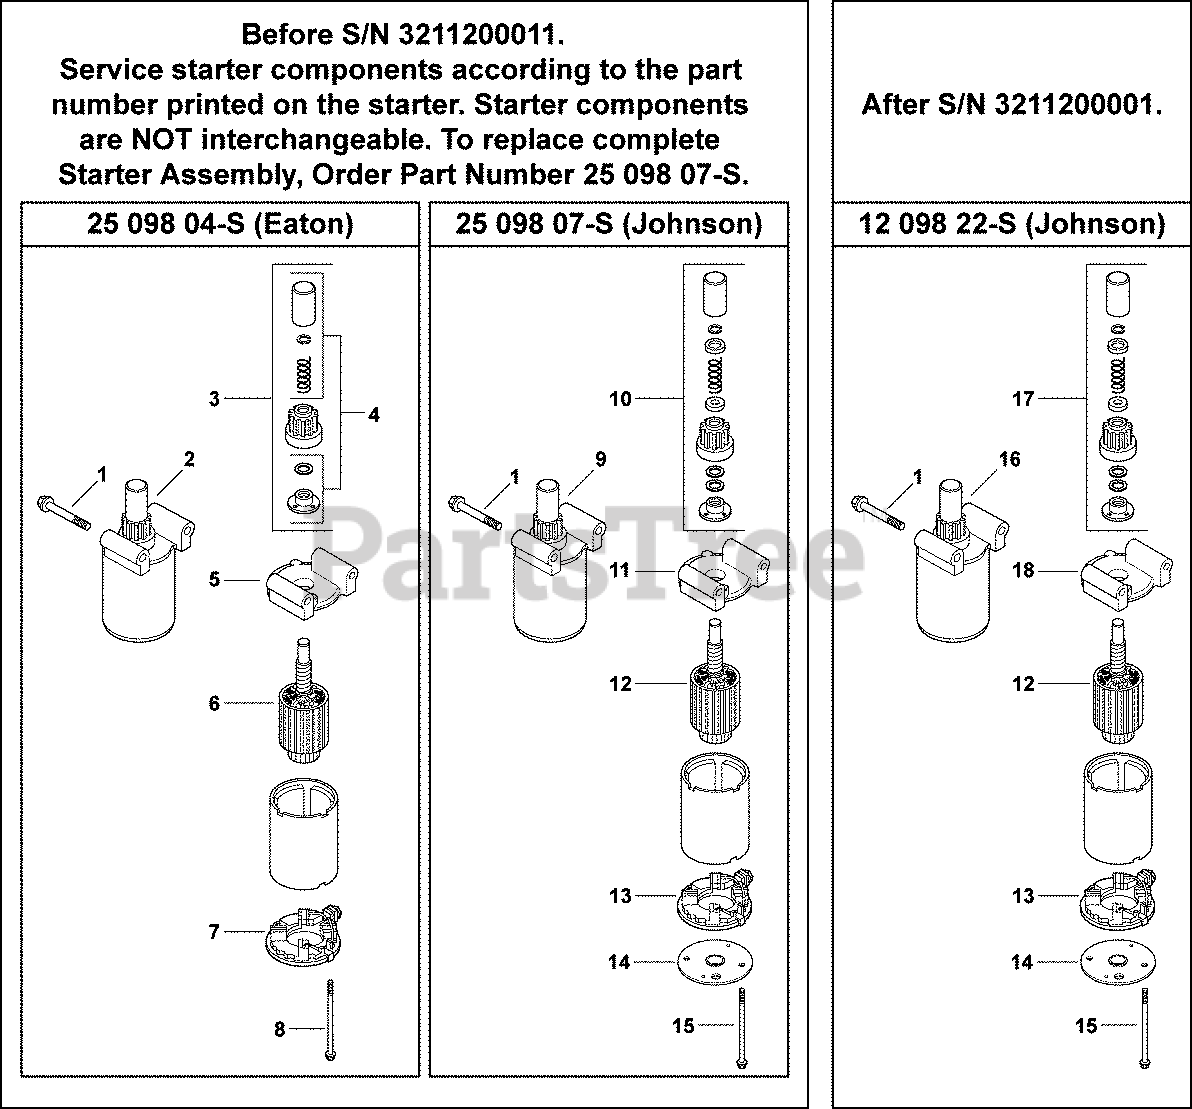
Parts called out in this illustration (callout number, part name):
1	SCREW, FLG M8X1.25X70
3	KIT,DR W/GEAR (FASCO/V.WEISE/W&G)(#DSC)
4	KIT, DR PTS(FASCO/V.WEISE/W&G) - DISC.
5	CAP, DRIVE END - DISCONTINUED
6	ARMATURE - (#DSC)
7	BRUSH ASSY (FASCO/V.WEISE/W&G)-DISC.
8	SCREW - DISCONTINUED
9	ELECTRIC STARTER-BENDIX DRIVE
10	KIT, DRIVE
11	CAP, DRIVE END - (#DSC)
12	ARMATURE - DISCONTINUED
13	BRUSH KIT - (#DSC)
14	CAP - DISCONTINUED
15	BOLT, THRU #10-24X4 13/32" - DISCONTINUED
16	ELECTRIC STARTER-BENDIX DRIVE
17	KIT, DRIVE
18	CAP, DRIVE END - (#DSC)
